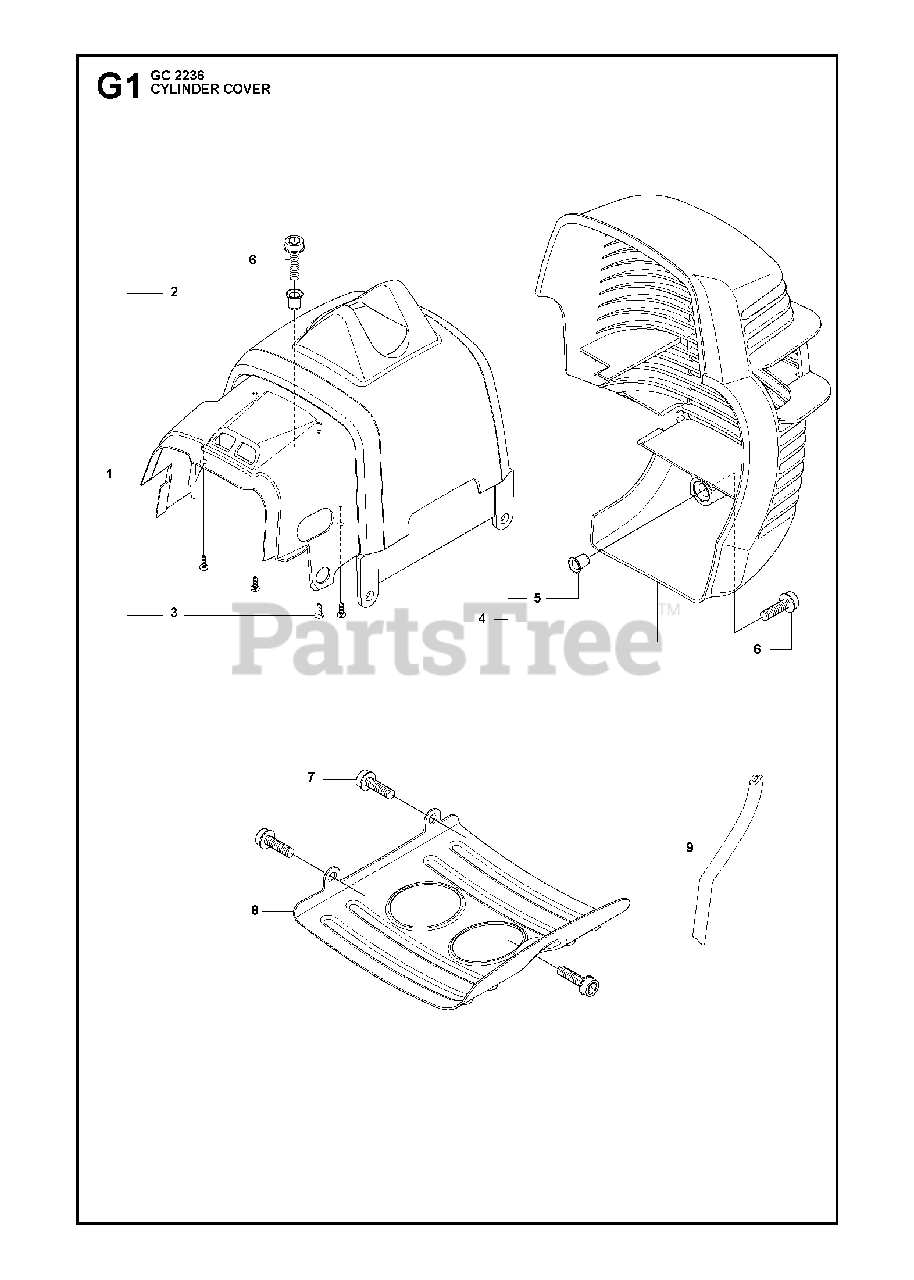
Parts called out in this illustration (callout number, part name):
2	SLEEVE
3	SCREW
5	SLEEVE
